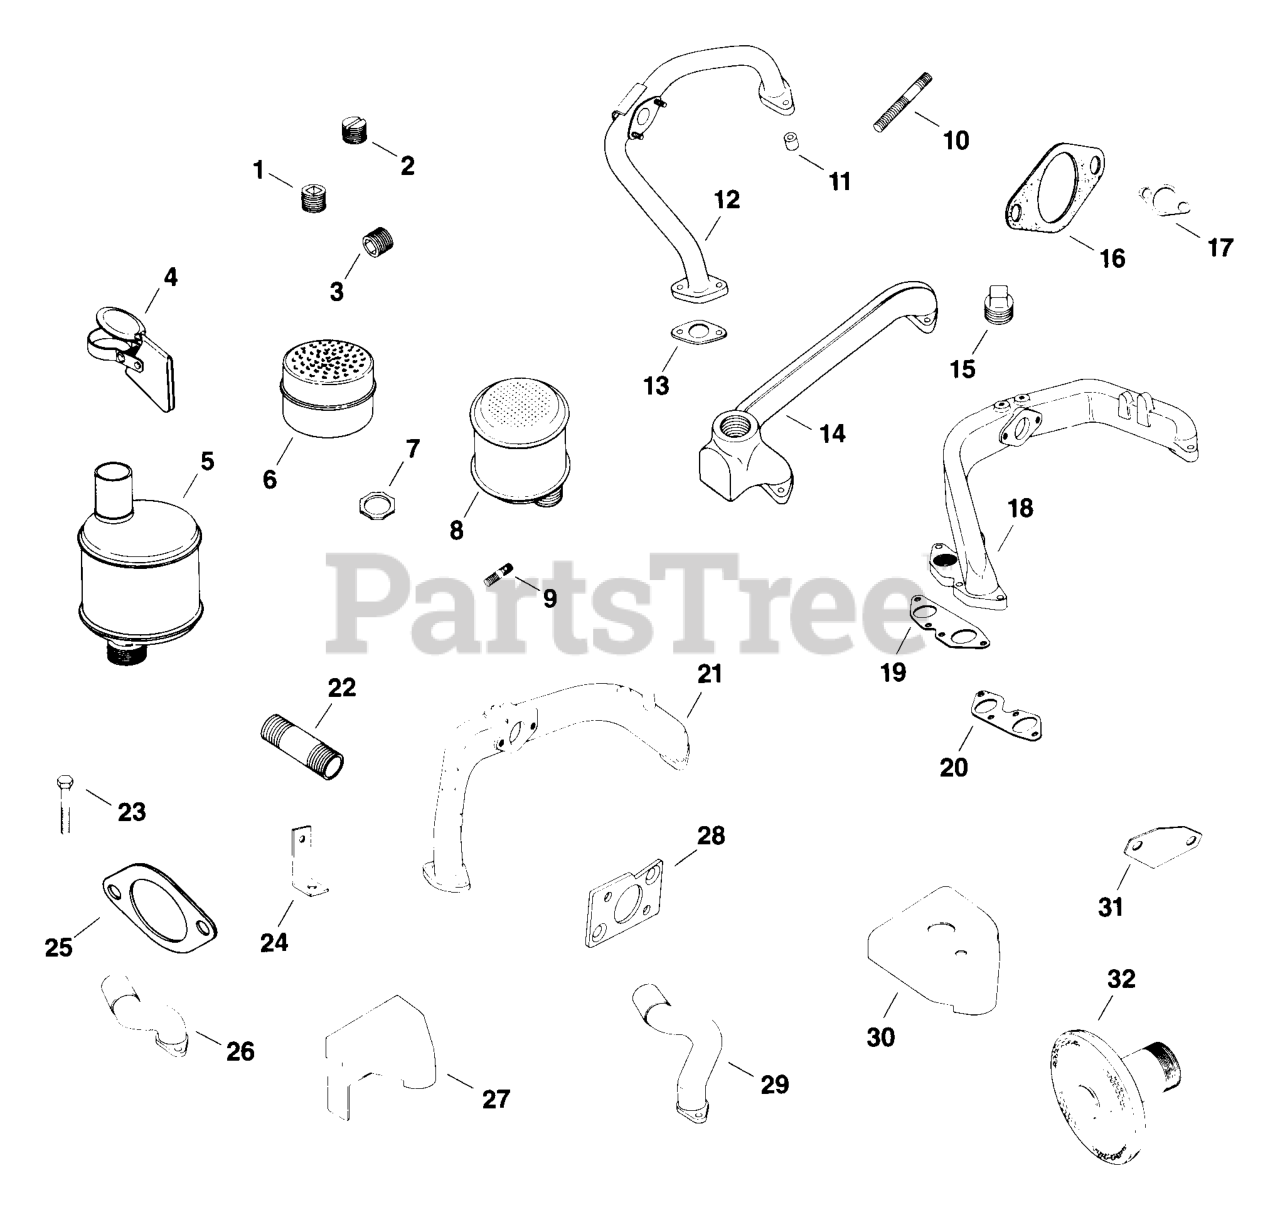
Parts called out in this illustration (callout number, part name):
1	PLUG, PIPE 1-1/2" USE 25 139 63-S
12	MANIFOLD - (#DSC)
13	GASKET, MANIFOLD-USE 25 041 11-S
14	MANIFOLD - DISCONTINUED
